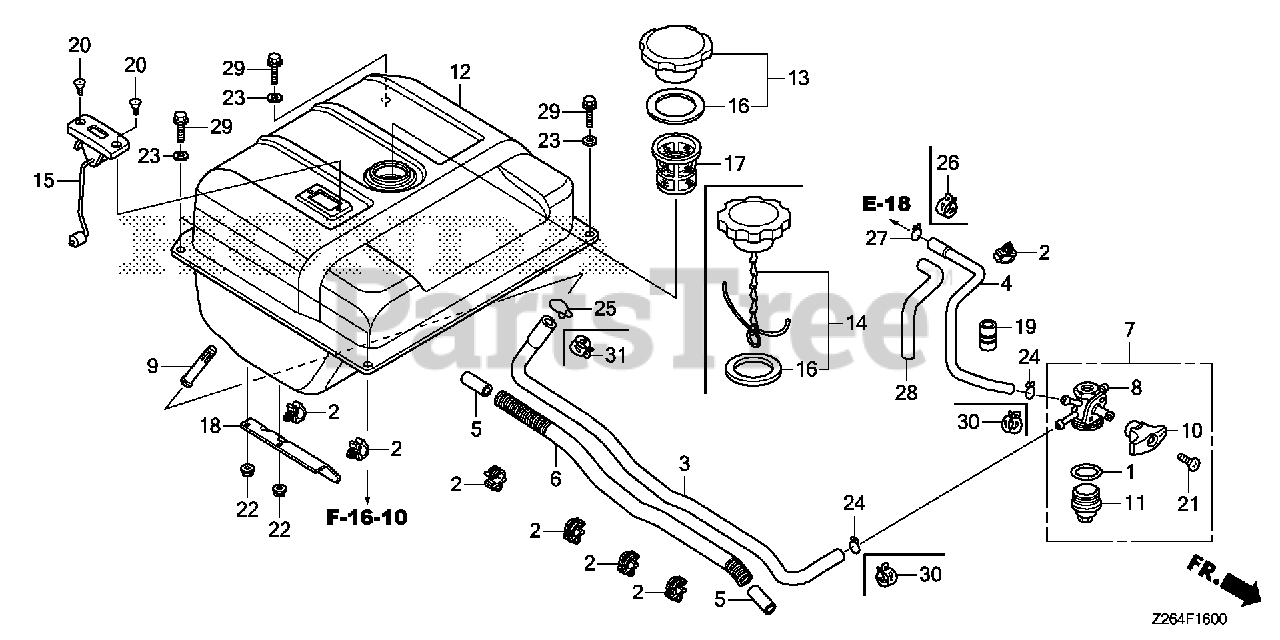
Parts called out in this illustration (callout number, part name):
1	GASKET, FUEL STRAINER CUP
2	CLIP, TUBE
3	TUBE, FUEL TANK (FKM)
4	TUBE, FUEL PETCOCK (FKM)
5	RUBBER, SUPPORTER
6	PROTECTOR, TUBE
7	PETCOCK ASSY.
8	BODY, PETCOCK
9	FILTER, FUEL
10	LEVER, PETCOCK
11	CUP, FUEL STRAINER
12	TANK, FUEL *R280* (POWER RED)
14	CAP, FUEL FILLER
15	METER ASSY., FUEL
16	GASKET, FUEL FILLER CAP
17	FILTER, FUEL
18	HOLDER, FUEL TUBE
19	RUBBER, FUEL (9X15X20)
20	SCREW, FLAT (5X10)
21	SCREW, OVAL (4X18)
22	NUT, FLANGE (5MM)
23	WASHER, PLAIN (6MM)
26	CLAMP, TUBE (D8.5)
28	BULK HOSE, VINYL (9X11X3000) (9X11X120)
29	BOLT, FLANGE (6X16)
30	CLAMP, TUBE (D8)
31	CLAMP, TUBE (D10.5)
